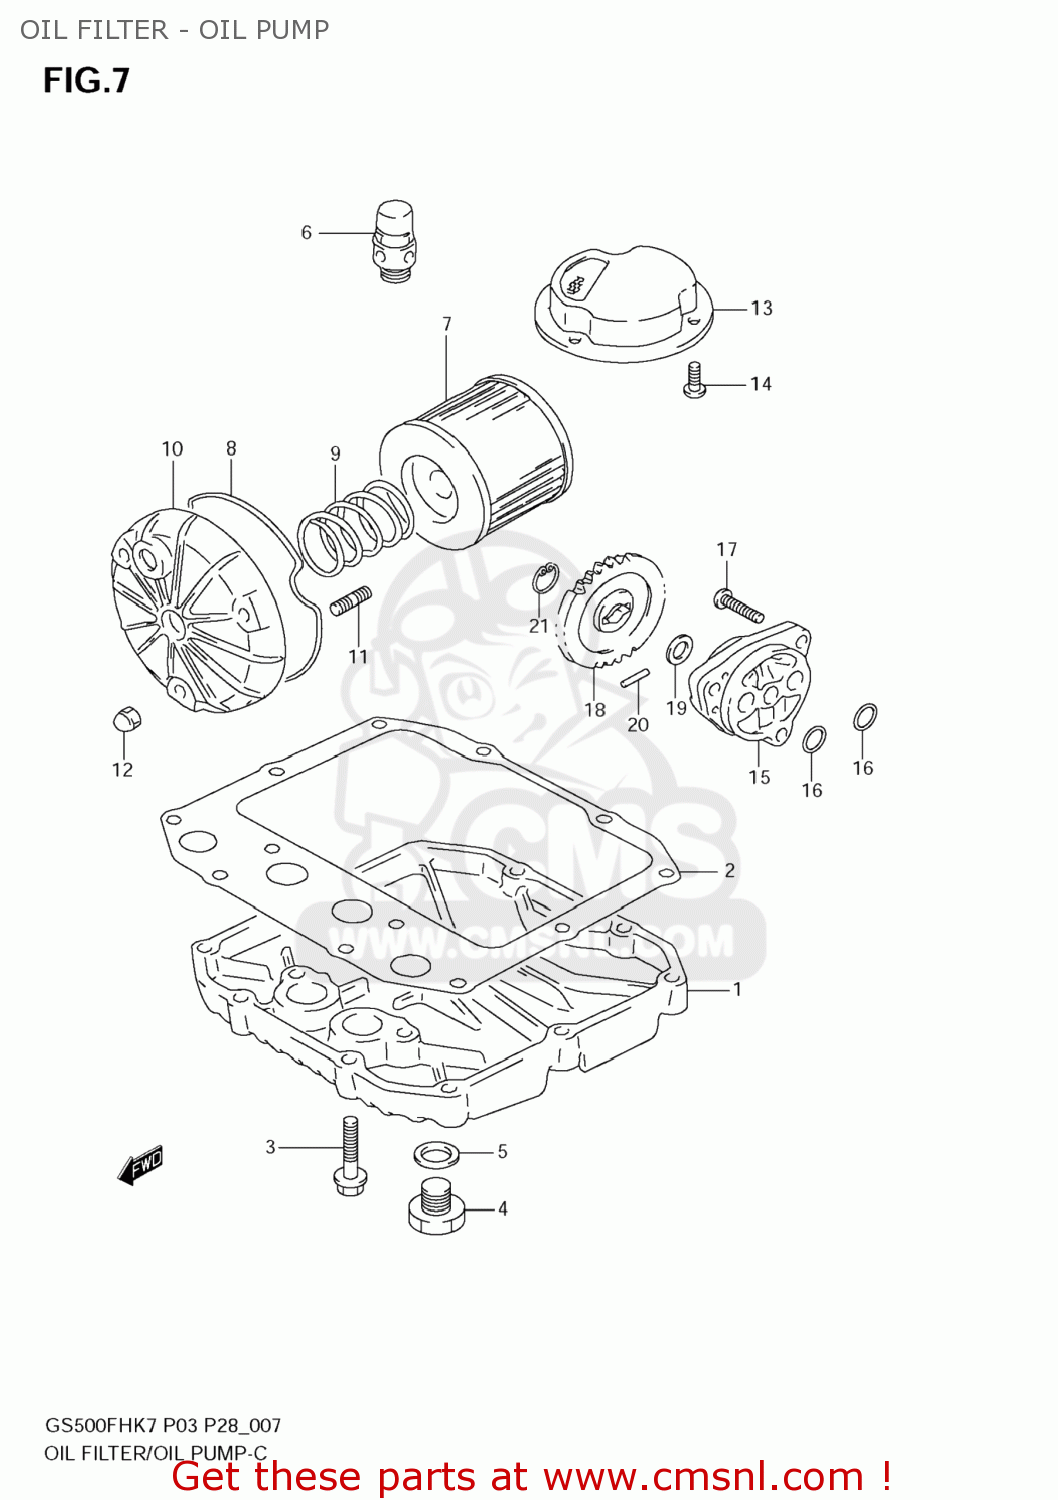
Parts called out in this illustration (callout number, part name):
1	PAN,OIL
2	GASKET,OIL PAN(ASB) (NAS)
3	BOLT
4	PLUG(14X12)
5	GASKET(13.8X18.8X4.8) (NAS)
6	REGULATOR,ENGINE OIL(6.5K)
7	FILTER ASSY,ENGINE OIL
8	O RING,OIL FILTER CHAMBER CAP
9	SPRING
10	CAP,OIL FILTER
11	BOLT,STUD
12	NUT
13	STRAINER,ENGINE OIL
14	BOLT
15	PUMP ASSY,ENGINE OIL
16	O RING(D:1.9,ID:13)
17	SCREW(6X25)
18	GEAR,OIL PUMP DRIVEN
19	SHIM(10X18X0.5)
20	PIN(4X15.8)
21	CIRCLIP
